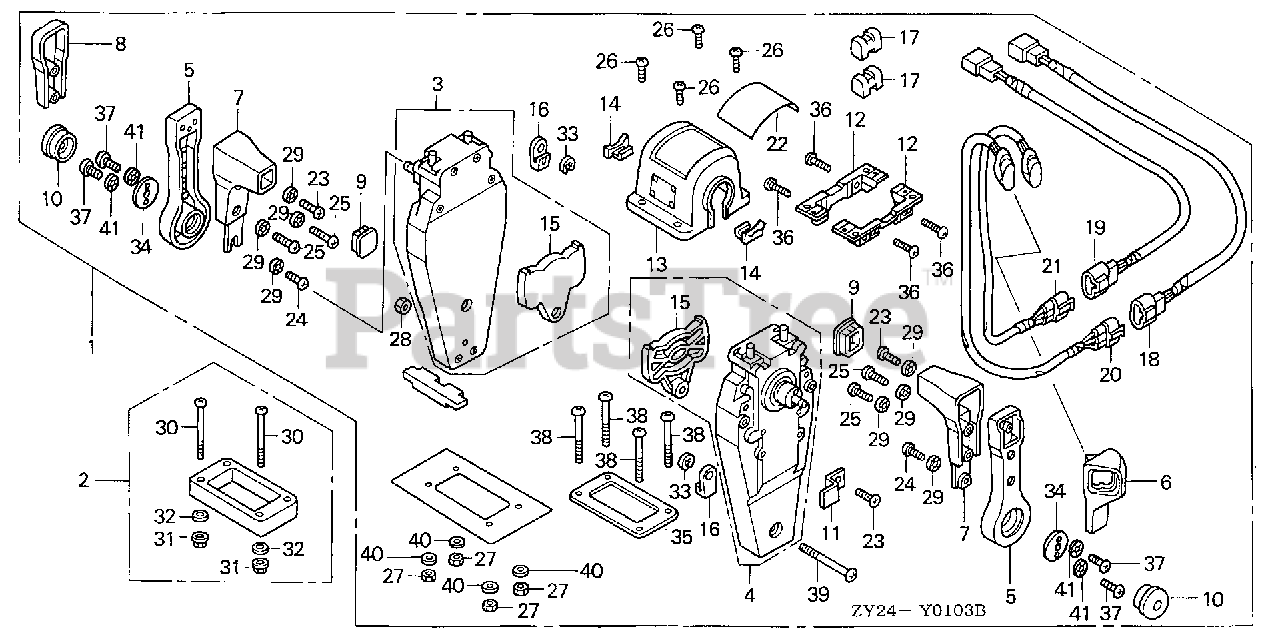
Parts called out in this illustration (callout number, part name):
1	BOX KIT, REMOTE CONTROL (TOP MOUNT DUAL)(L)
2	SPACER KIT, REMOTE CONTROL BOX (TOP MOUNT DUAL)
3	HOUSING ASSY., L. (INNER) (TOP MOUNT)
4	HOUSING ASSY., R. (INNER) (TOP MOUNT)
5	HANDLE, REMOTE CONTROL
6	COVER, R. GRIP
7	GRIP, REMOTE CONTROL HANDLE
8	COVER, DUAL GRIP
9	CAP, GRIP
10	BUTTON, THROTTLE
11	PLATE, CABLE CLAMP
12	BRACKET, REMOTE CONTROL HOUSING
13	HOUSING, DUAL REMOTE CONTROL BOX
14	HOUSING, LEAD
15	PLATE, DWELL
16	TERMINAL, CABLE
17	SPACER, CABLE CLAMP
18	SUB-HARNESS ASSY., POWER TRIM-TILT (A)
19	SUB-HARNESS ASSY., POWER TRIM-TILT (B)
20	SWITCH ASSY., POWER TRIM-TILT (A)
21	SWITCH ASSY., POWER TRIM-TILT (B)
22	MARK, REMOTE CONTROL (DUAL)
23	SCREW, PAN (5X16)
24	SCREW, PAN (5X10)
25	SCREW, PAN (5X20)
26	SCREW, PAN (4X10)
27	NUT, HEX. (5MM)
28	NUT, HEX. (5MM)
29	WASHER, LOCK (5MM)
30	SCREW, PAN (5X65)
31	NUT, FLANGE (5MM)
32	WASHER, PLAIN (5MM)
33	E-RING (6MM)
34	PLATE, HANDLE
35	GASKET, DUAL
36	SCREW, PAN (5X18)
37	SCREW, PAN (6X18)
38	SCREW, PAN (5X40)
39	SCREW, PAN (5X55)
40	WASHER, LOCK (6MM)
41	WASHER, PLAIN (5MM)
